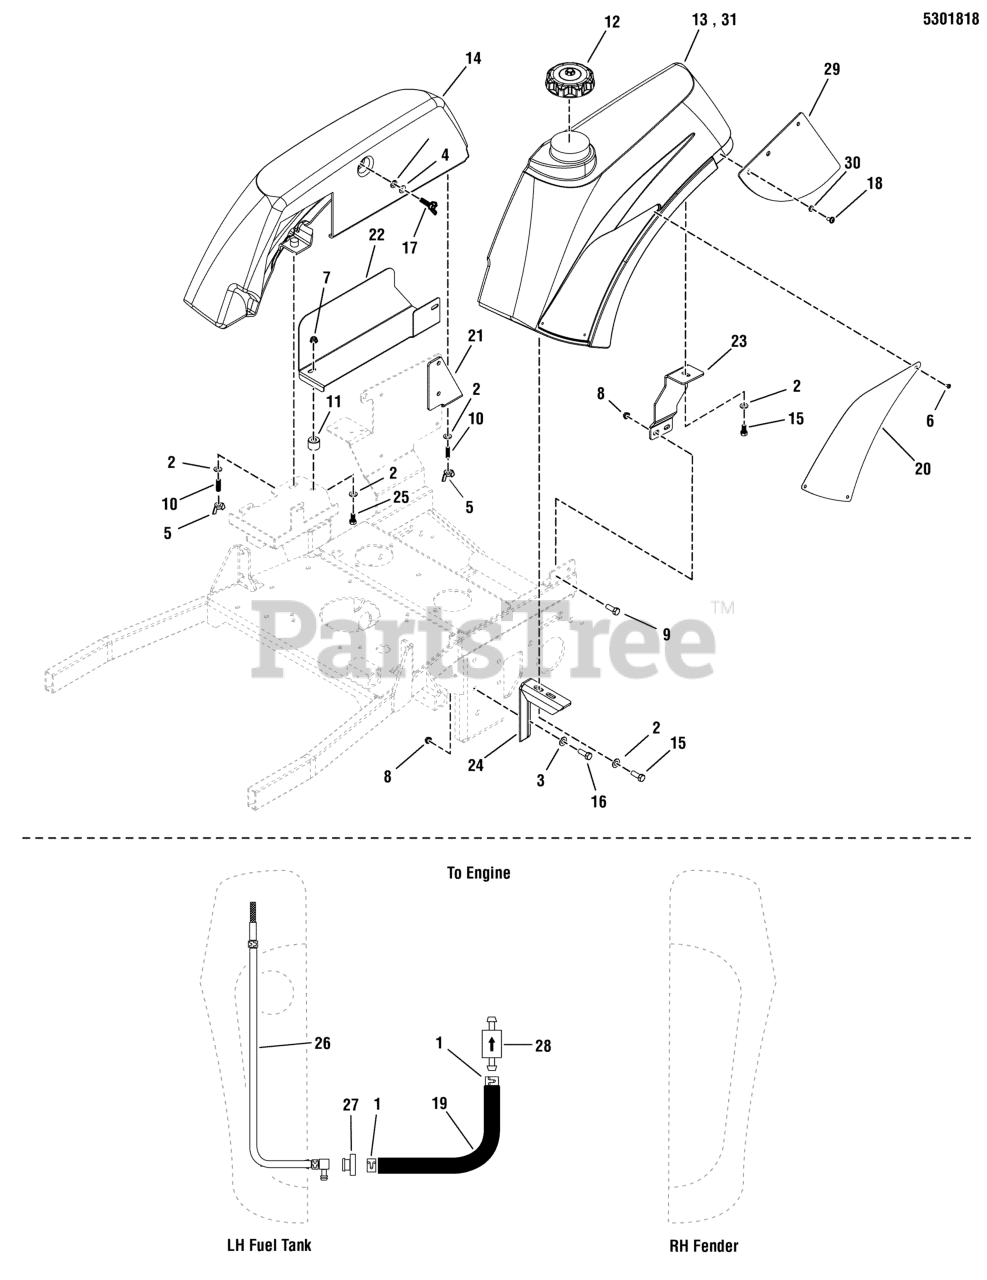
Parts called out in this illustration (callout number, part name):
1	CLAMP, HOSE, EXTERNAL, 1/2 - RED
2	WASHER, 5/16" SAE
3	WASHER, 3/8 SAE
4	WASHER, 5/16 LOCK CZ
5	NUT, 5/16-18 WING NYLON LOCK
6	SCREW, #10-24 X 3/8 ALLEN BHBZ
7	NUT, 5/16-18 HEX NYLOCK FLANGE
8	NUT, 3/8-16 HEX NYLOCK FLANGE
9	SCREW, BUTTON HD. SOC CAP, 3/8-16X1. BZ
10	SOC SET SCREW, 5/16-18 X 1-1/2 SS
11	SPACER, .39 X 1.00 X .80
12	CAP, GASOLINE, VENTED
12	FUEL CAP, 3-1/2", MANAGED VENT OUT, 12"
13	FUEL TANK, EVOLUTION, 48/52
14	FENDER, EVOLUTION, 48/52
15	BOLT, 5/16-18 X 3/4 GD5
16	BOLT, 3/8-16 X 1" GD5 CZ
17	WING, SCREW, 5/16-18 X 1-1/4, CZ
18	SCREW, 1/4-20 X 1/2 ALLEN BH
19	HOSE, 1/4" FUEL, 24.00"
20	PLATE, BADGE EVOLUTION, 52 - RED
21	PLATE, RIGHT REAR TANK MOUNT - RED
22	GUARD, OIL FILTER - RESERVOIR, EVO - RED
23	PLATE, REAR TANK MOUNT, 48 - RED
24	WELD, MOUNT, FUEL TANK, FRONT - RED
25	BOLT, 5/16-18 X 1-1/2 GD5 YZ
26	PICKUP TUBE ASM, FUEL TANK, 18.38" (SV)
27	BUSHING-FUEL TANK RED RUBBER
28	FUEL FILTER (SV)
29	FLAP, GUARD, 48/52
30	WASHER, 1/4 SAE
31	FUEL TANK, EVOLUTION, 48/52
